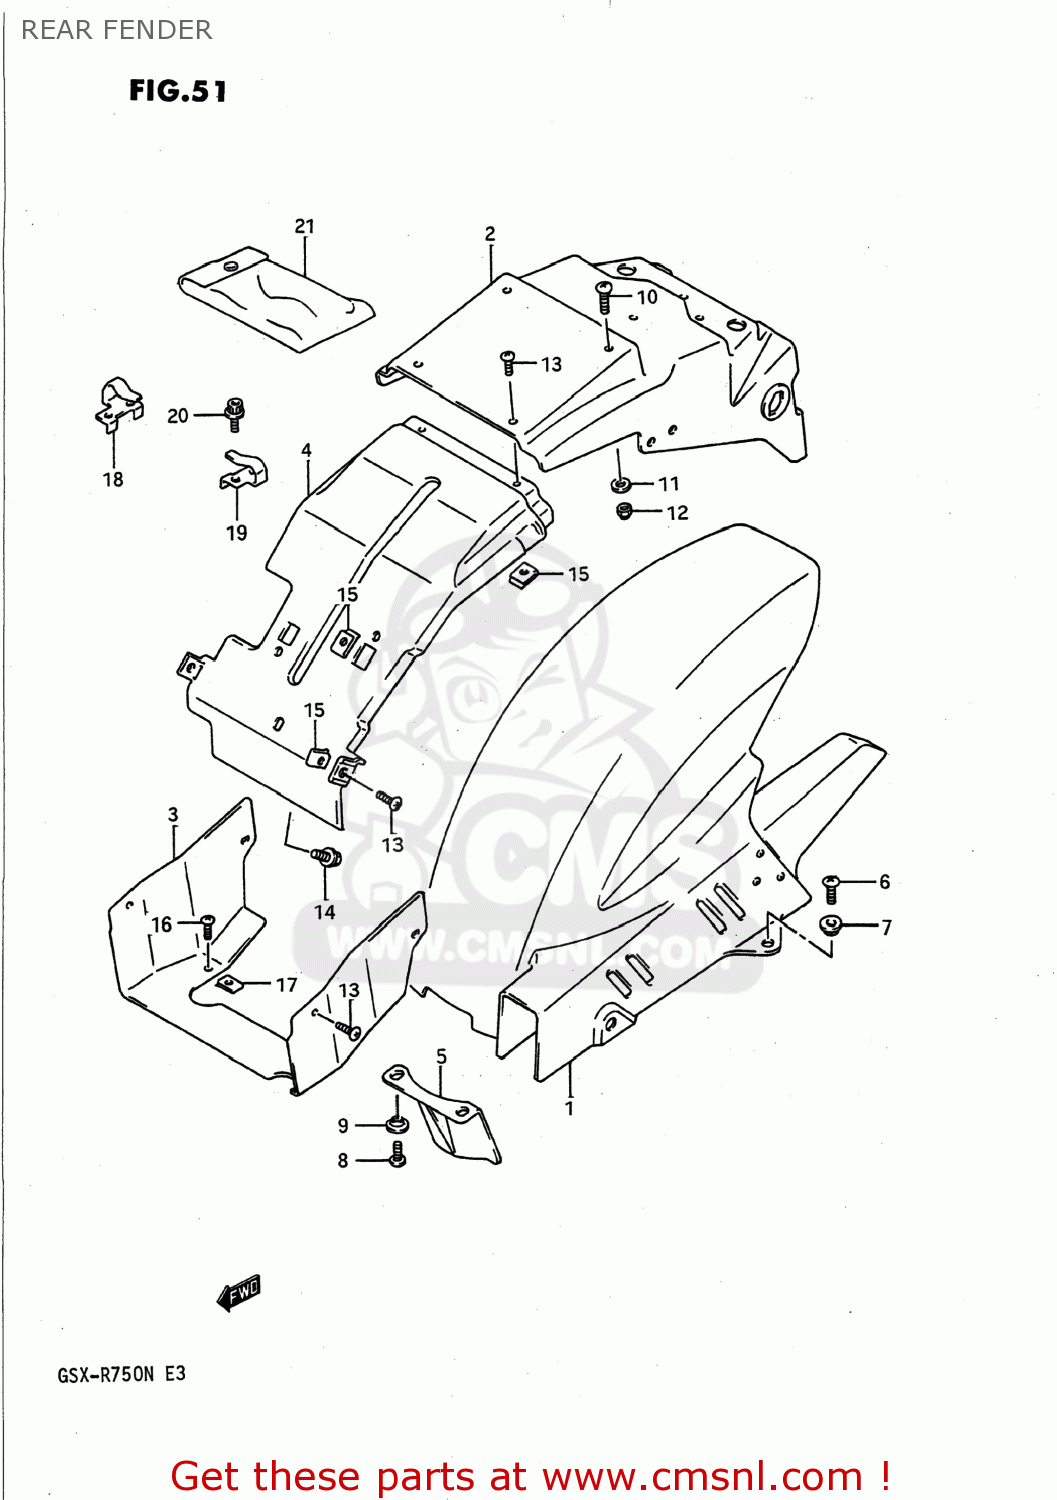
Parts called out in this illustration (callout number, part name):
1	FENDER,RR LWR
2	FENDER,RR UPR
3	FENDER,REAR
4	FENDER,RR UPR FR NO.2
5	GUARD,RR UNIT MUD
6	SCREW
7	WASHER
8	SCREW
9	WASHER,LOCK
10	SCREW
11	WASHER
12	NUT
13	SCREW, FRONT & REAR
14	BOLT
15	NUT,HEADLAMP HOUSING,UPPER
16	SCREW, FRONT & REAR
17	NUT,HEADLAMP HOUSING,UPPER
18	HOLDER,HELMET,R
19	HOLDER,HELMET,L
20	BOLT
21	TOOL ASSY
